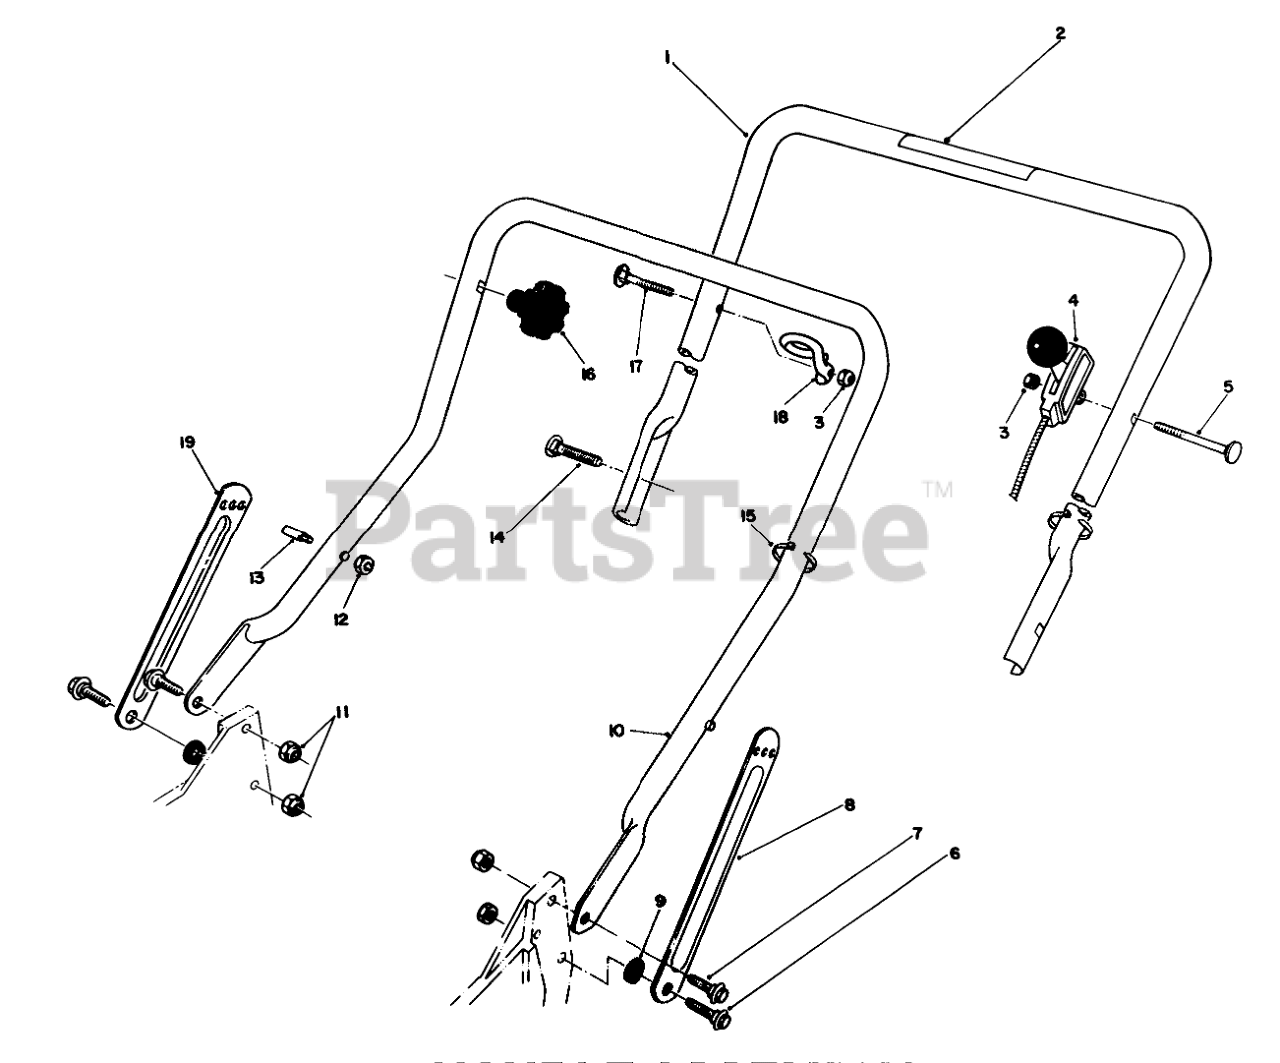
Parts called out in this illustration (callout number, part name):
1	Handle-Upper (Incl Ref. #2)
2	DECAL - HANDLE
3	NUT-LOCK, NI
4	THROTTLE CONTROL
5	SCREW-HANDLE
6	SCREW-SHOULDER
7	SCREW-SHOULDER
8	LH HANDLE LATCH
9	SPACER
10	LOWER HANDLE ASM
11	NUT-LOCK, NI
12	NUT-LOCK, NI
13	HANDLE PIN
14	5/16-18 X 2 HNDLE SCREW
15	TIE-CABLE
17	HANDLE SCREW
18	Guide
19	RH HANDLE LATCH
